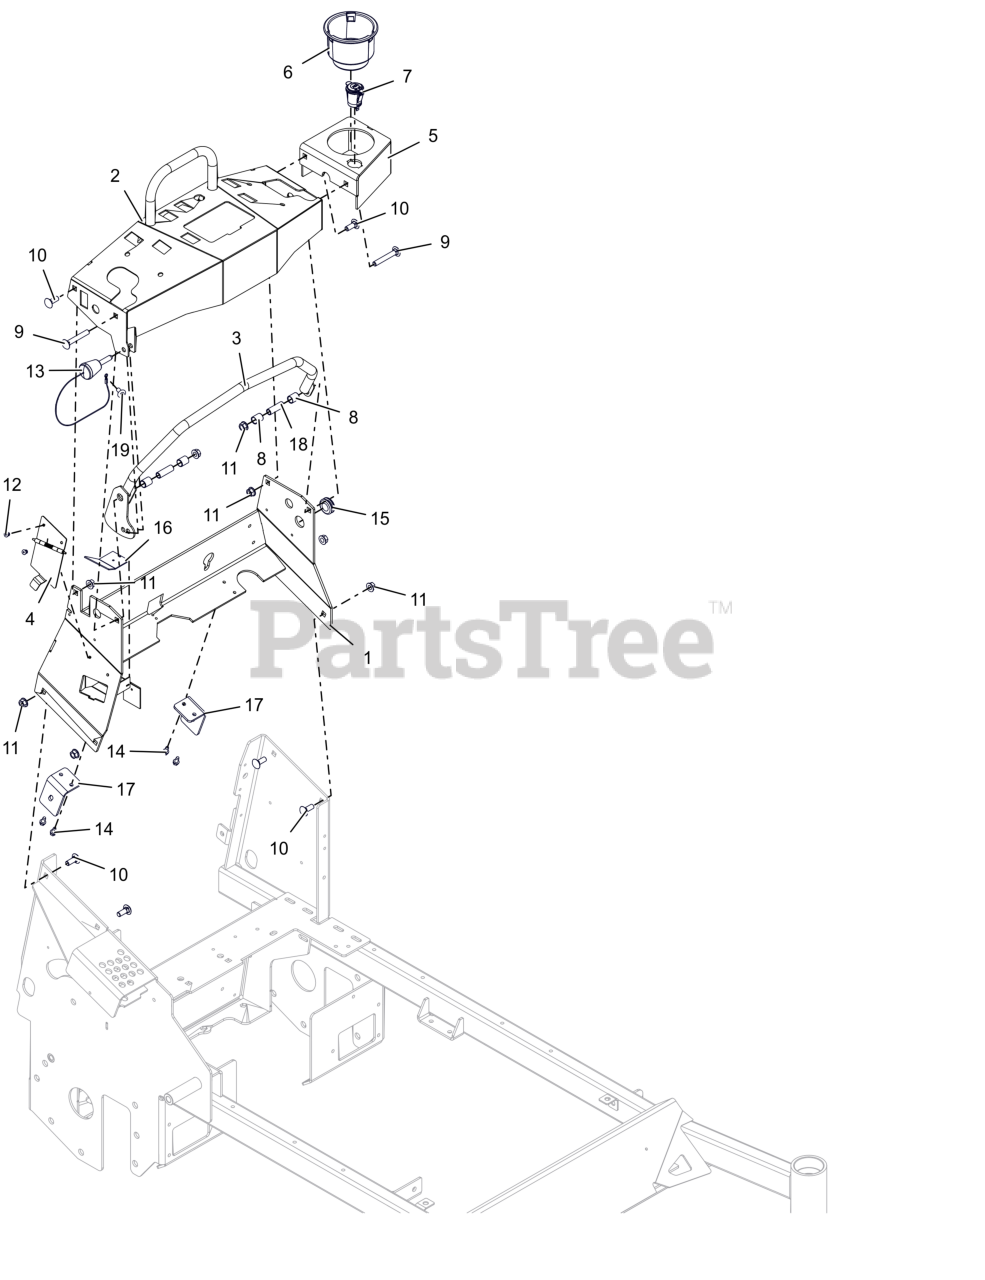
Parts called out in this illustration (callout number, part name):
1	WLDMT- TOWER
2	WLDMT- DASH
3	WLDMT- CRUISE BAR
4	ASM, CHARGER COVER
5	WLDMT- CUP HOLDER
6	CUPHOLDER, SNAP-IN 3.75OD
7	PORT, 12 VOLT POWER
8	BRG- .500 X .625 X .750
9	BLT,RHSN .38-16X2.50 G5 ZCC
10	BLT, RHSN .38-16X1.00 G5 ZCC
11	NUT-LK-CTR-FLG .375-16 GF ZCC
12	RVT, POP .187x.250 MULTIGRIP AL
13	PIN- MAGNETIC .375 X 1.5
14	SCR-TAP .25-20X.50 HWH ZCC
15	GROMMET,RUBBER.688 IDX1.000 OD
16	COVER- CHARGER BRACKET
17	BRKT- DAMPER MTG
18	SPCR, SLV .375 X .625 X 1.54
19	XMAS TREE FASTNER-BLACK
